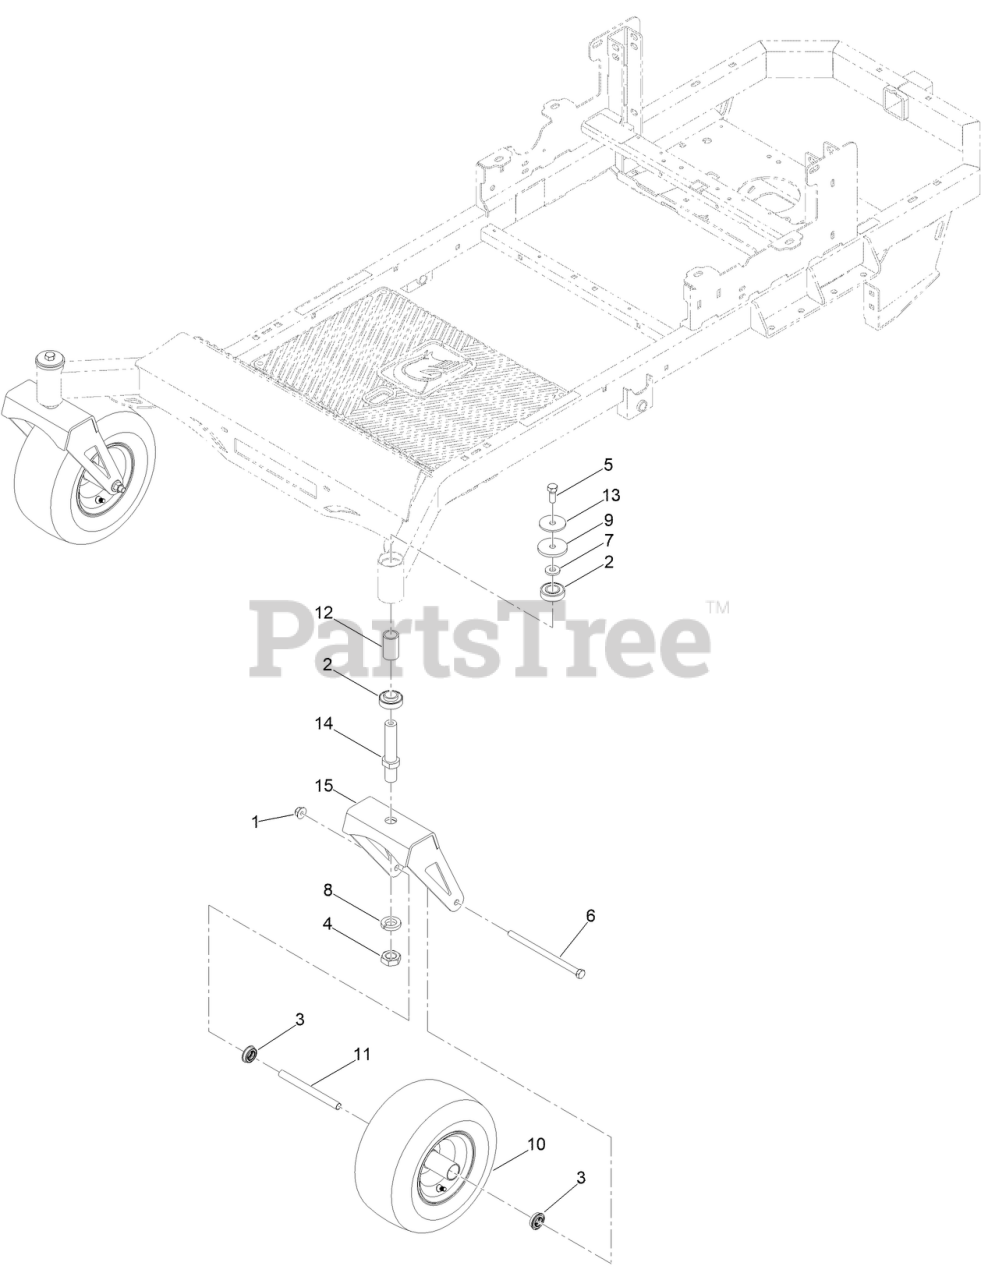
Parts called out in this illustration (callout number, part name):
1	NUT-LOCK
2	BEARING-BALL
3	RZ FT WHEEL BEARING
5	1/2-20 X 1-1/4 HEX FLANGE BOLT GR 8 YZ
6	1/2-13 X 8-1/2 HEX C/S GR 5 ZINC YELLOW
7	1/2 FENDER WASHER 1-1/4IN OD ZINC
8	1IN L/W MED SPLIT ZC
9	FT HUB PLASTIC WASHER
10	RZ/RT PRO FT TIRE ASSY-SMOOTH TREAD
11	MWR FT WHEEL SPANNER
12	CASTER FORK SHAFT BEARING SPACER
13	MWR CASTER SHAFT WASHER
14	MWR CASTER SHAFT
15	RZ CASTER FORK ASM
